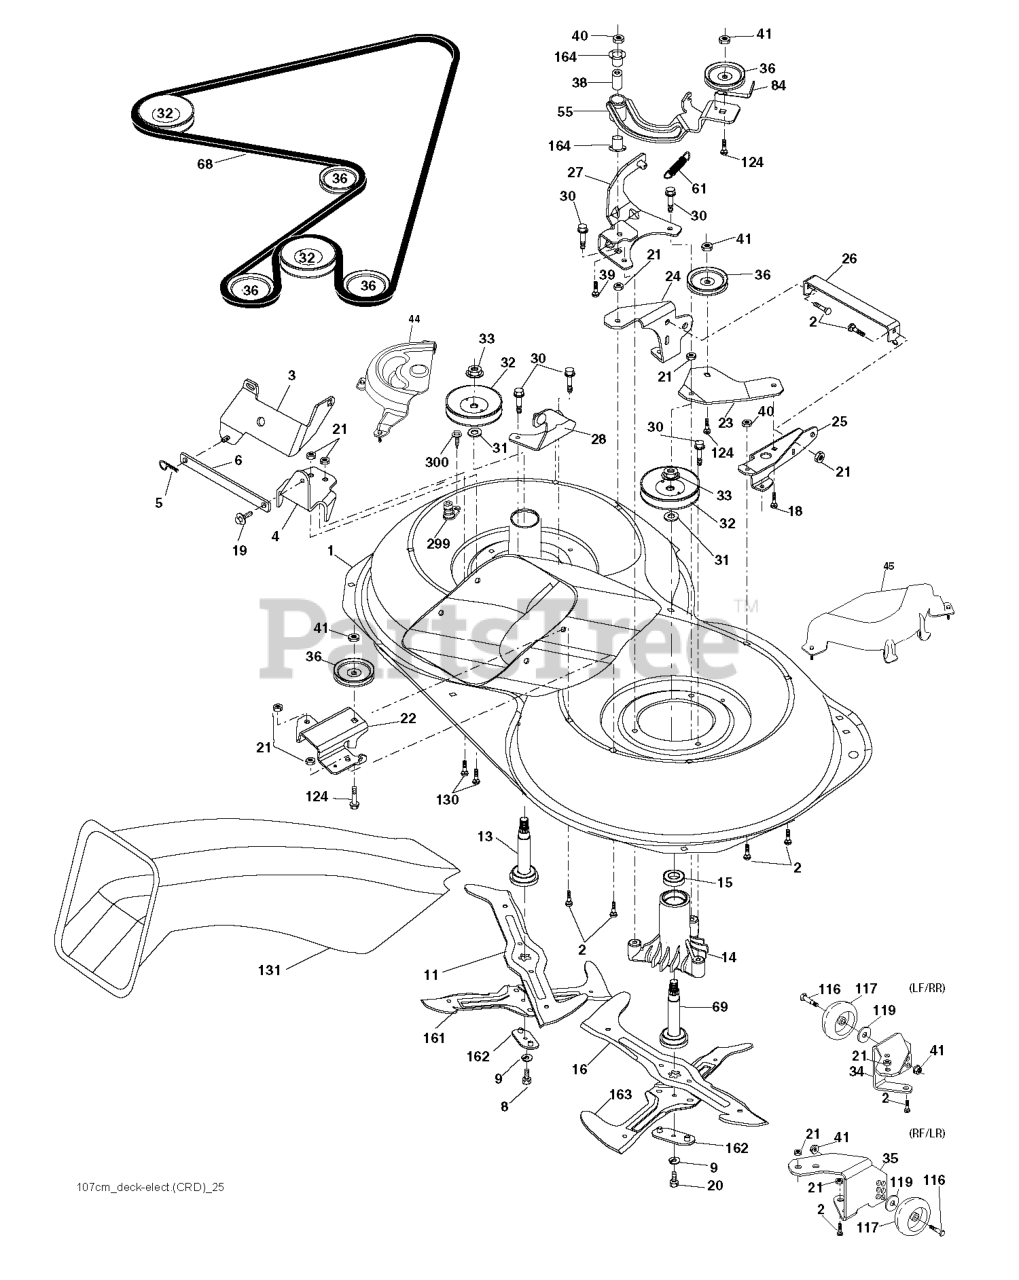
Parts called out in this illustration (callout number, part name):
1	Housing Asm. Mower 107 CRD
2	RP BOLT 5/16-18 X3/4 ZN/YEL GR
3	BRACKET.ASM.BAR.SWAY.CHASS
5	RETAINER-SPRNG RB
6	BAR.SWAY.92.CRD
8	BOLT.3/8-24X1.25 GR8
9	LOCKWASHER
11	BLADE.3N1.LH.CRD
13	SHAFT ASM VENT
14	HOUSING.MANDREL.VENTED (MACHD)
16	BLADE.3N1.RH.CRD
19	BOLT SHD 5/16-18
20	BOLT.3/8-24X1.25GR8. LHTHRD
21	LOCKNUT
22	BRACKET.IDLER.RR.107.CRD
24	BRACKET
25	BRACKET RF
26	SUPPORT
28	BRACKET
30	SCREW, WASHER HEAD
31	WASHER.SPACER.MANDREL
32	PULLEY.MANDREL.4.80 PD.2006
33	NUT.FLANGE.LOCK.TOP
34	BRACKET
35	BRACKET
36	PULLEY.IDLER.4.25
41	NUT LOCK FLG 3/8-16 UNC
55	ARM.IDLER.107.CRD
61	SPRING
68	HEX-BELT 107 MOWER
69	SHAFT.ASM.W/LWR.BRG.RH.THREAD
84	KEEPER, BELT IDLER
116	BOLT.SHOULDER.3/8-16X3-5/8.
117	RP WHEEL. GUAGE RALLY
119	WASHER
124	BOLT.3/8-16X1.50
130	BOLT.CARR.SQNK.5/16-18UNC.X3/4
131	CHUTE BAGGER
163	BLADE.CROSS.RH.CRD.107
164	BRNG T
299	PORT.WASHOUT
300	SCREW.TT.#10-32X.5.3/8.FLANGE
